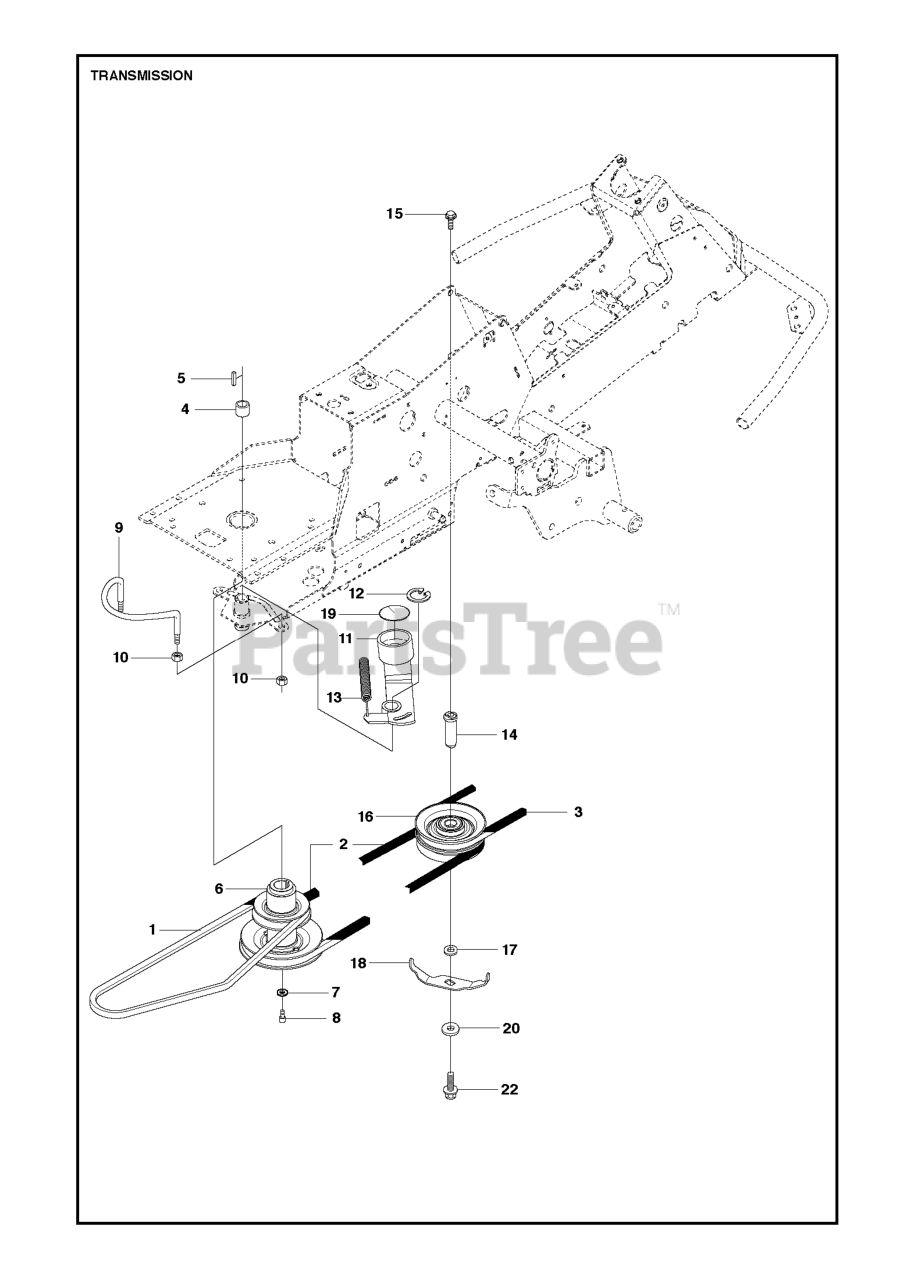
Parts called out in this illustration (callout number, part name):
10	NUT
12	RETAINING RING SGA 25
17	Screw M10x25
18	BELT GUIDE
